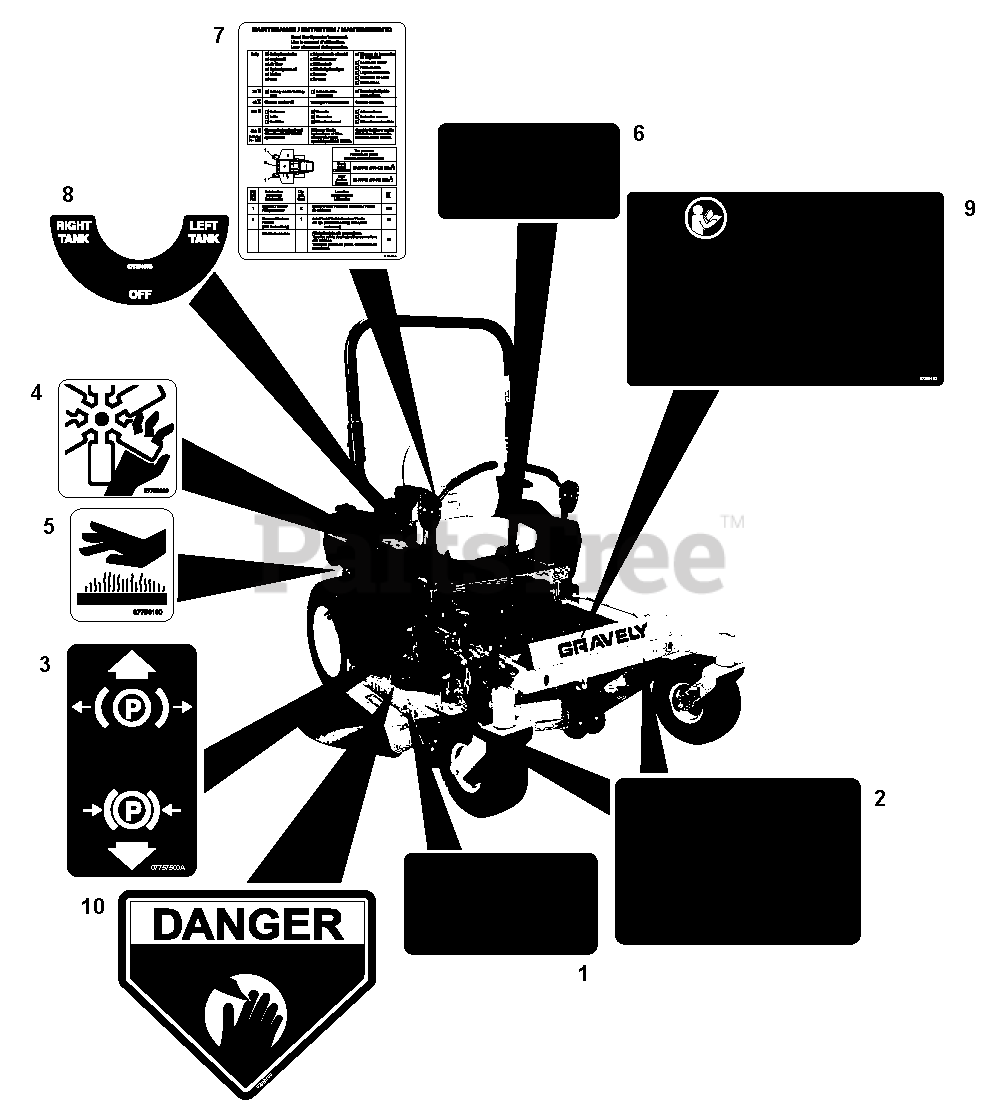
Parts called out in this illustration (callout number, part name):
1	Decal, Safety Deck Guarding
2	Decal, Safety Mower Deck
3	Decal, Parking Brake Lever
4	Decal, Danger Fan
5	Decal, Hot Surface
6	Decal, Safety Guarding
7	Decal, Maintenance Instructions
8	Decal, Fuel Control Valve
9	Decal, Main Safety Commercial
10	Decal, Danger
